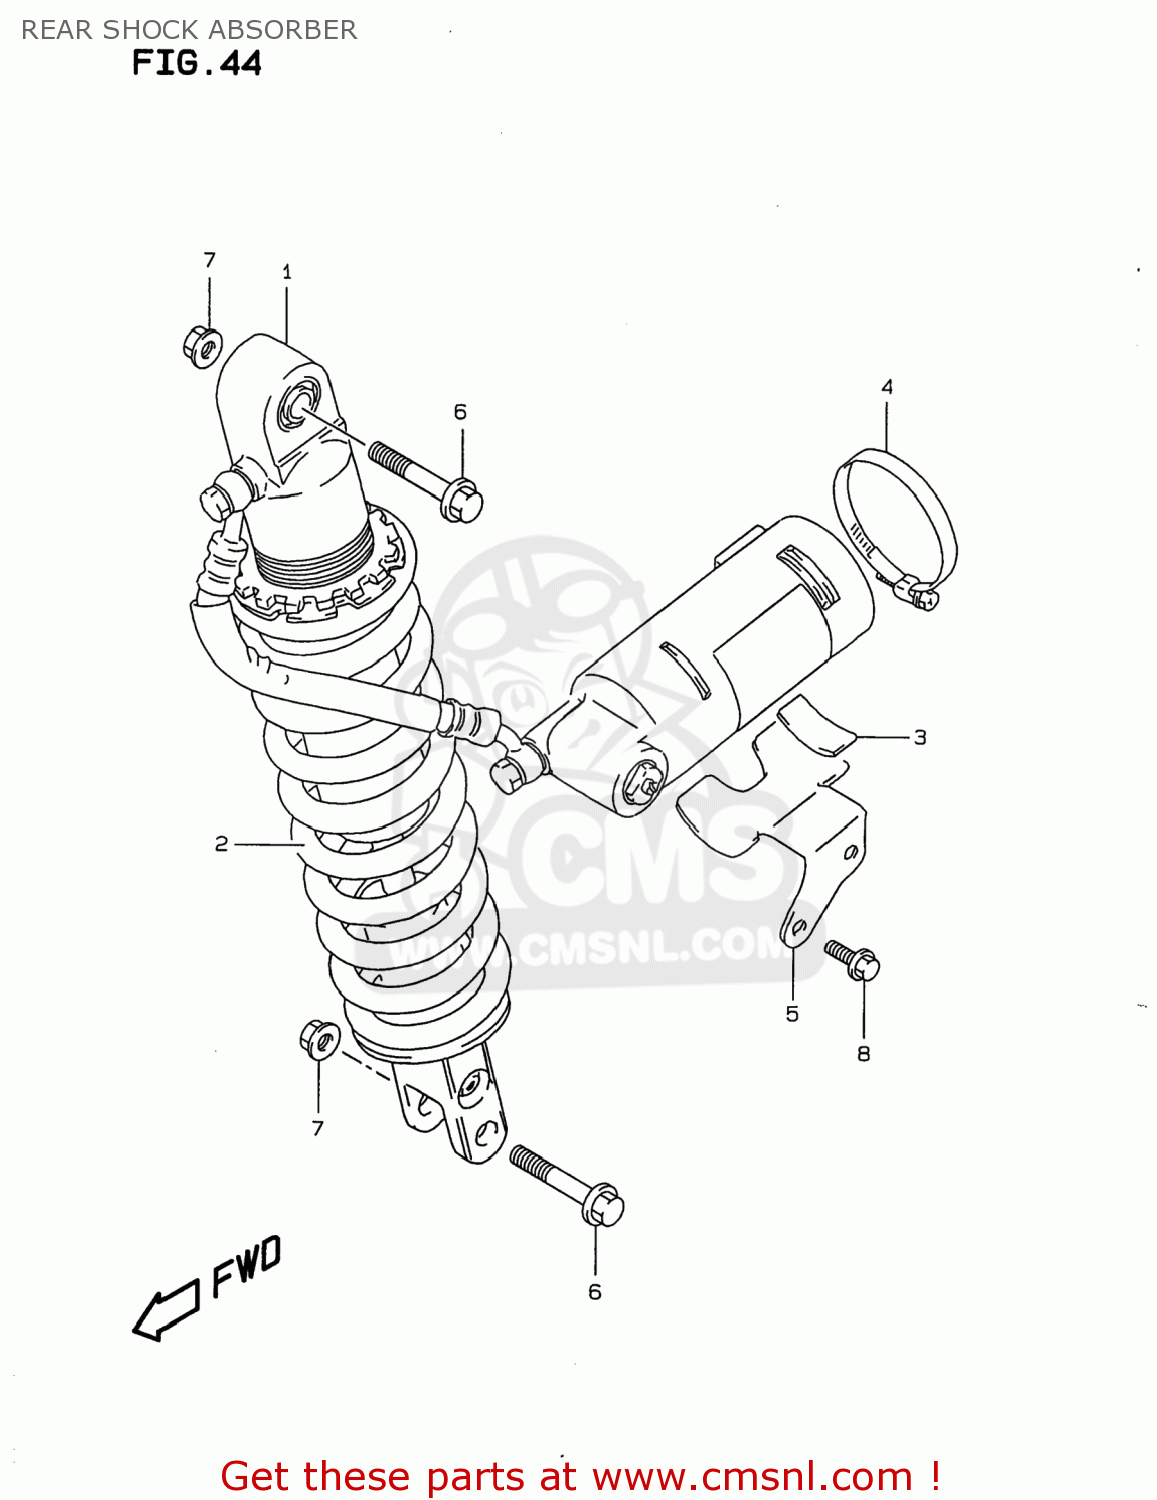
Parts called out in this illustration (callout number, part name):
1	ABSORBER ASSEMBLY,REAR SHOCK
2	SPRING
3	CUSHION
4	CLAMP
5	BRACKET,RESERVOIR TANK
6	BOLT,RR SHOCK ABSORBER
7	NUT
8	BOLT
